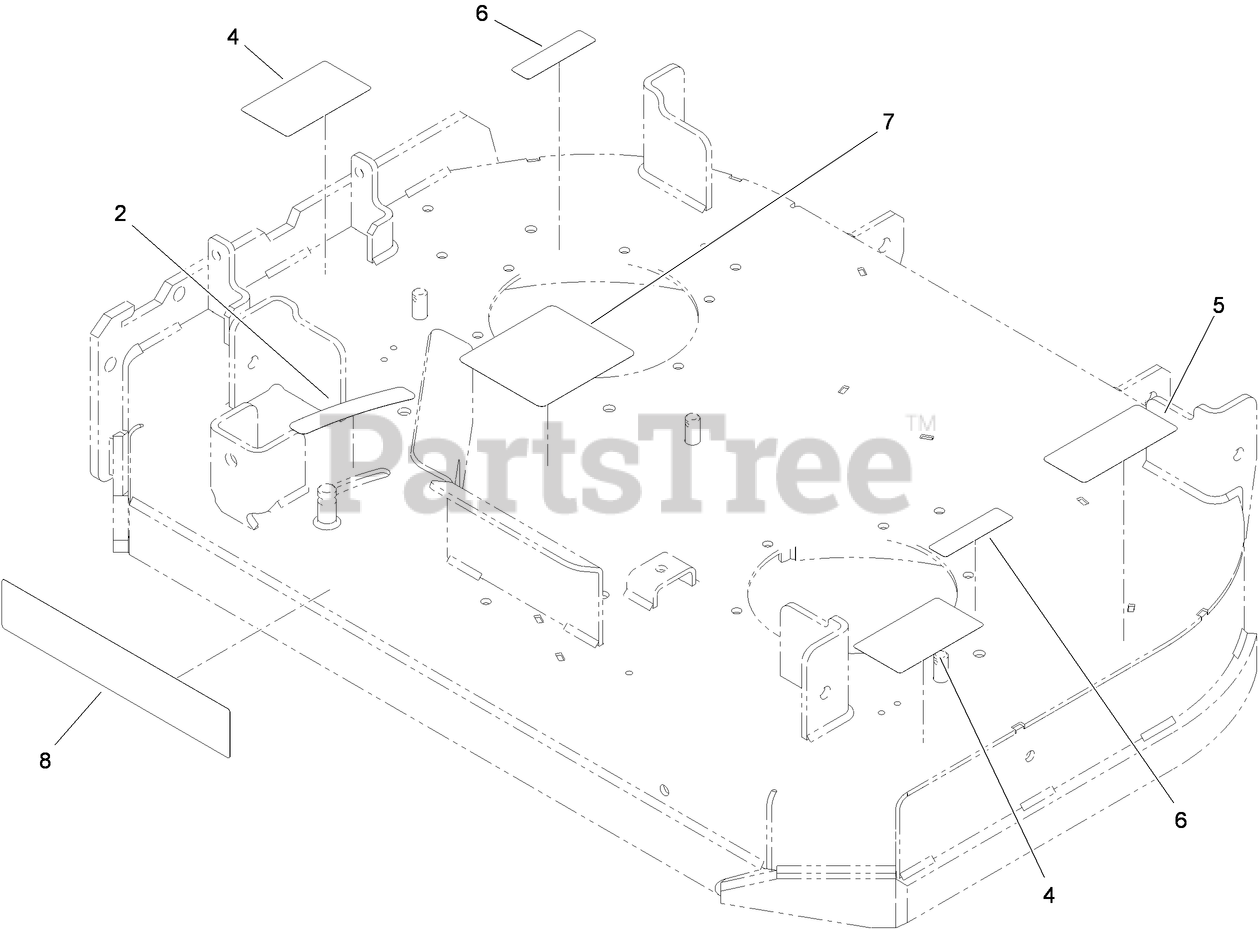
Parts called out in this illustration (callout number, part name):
2	DECAL-SETTING, BAFFLE
4	DECAL-DANGER
5	DECAL-TORQUE, BLADE BOLT
6	DECAL-DANGER
7	DECAL-ROUTING, BELT
